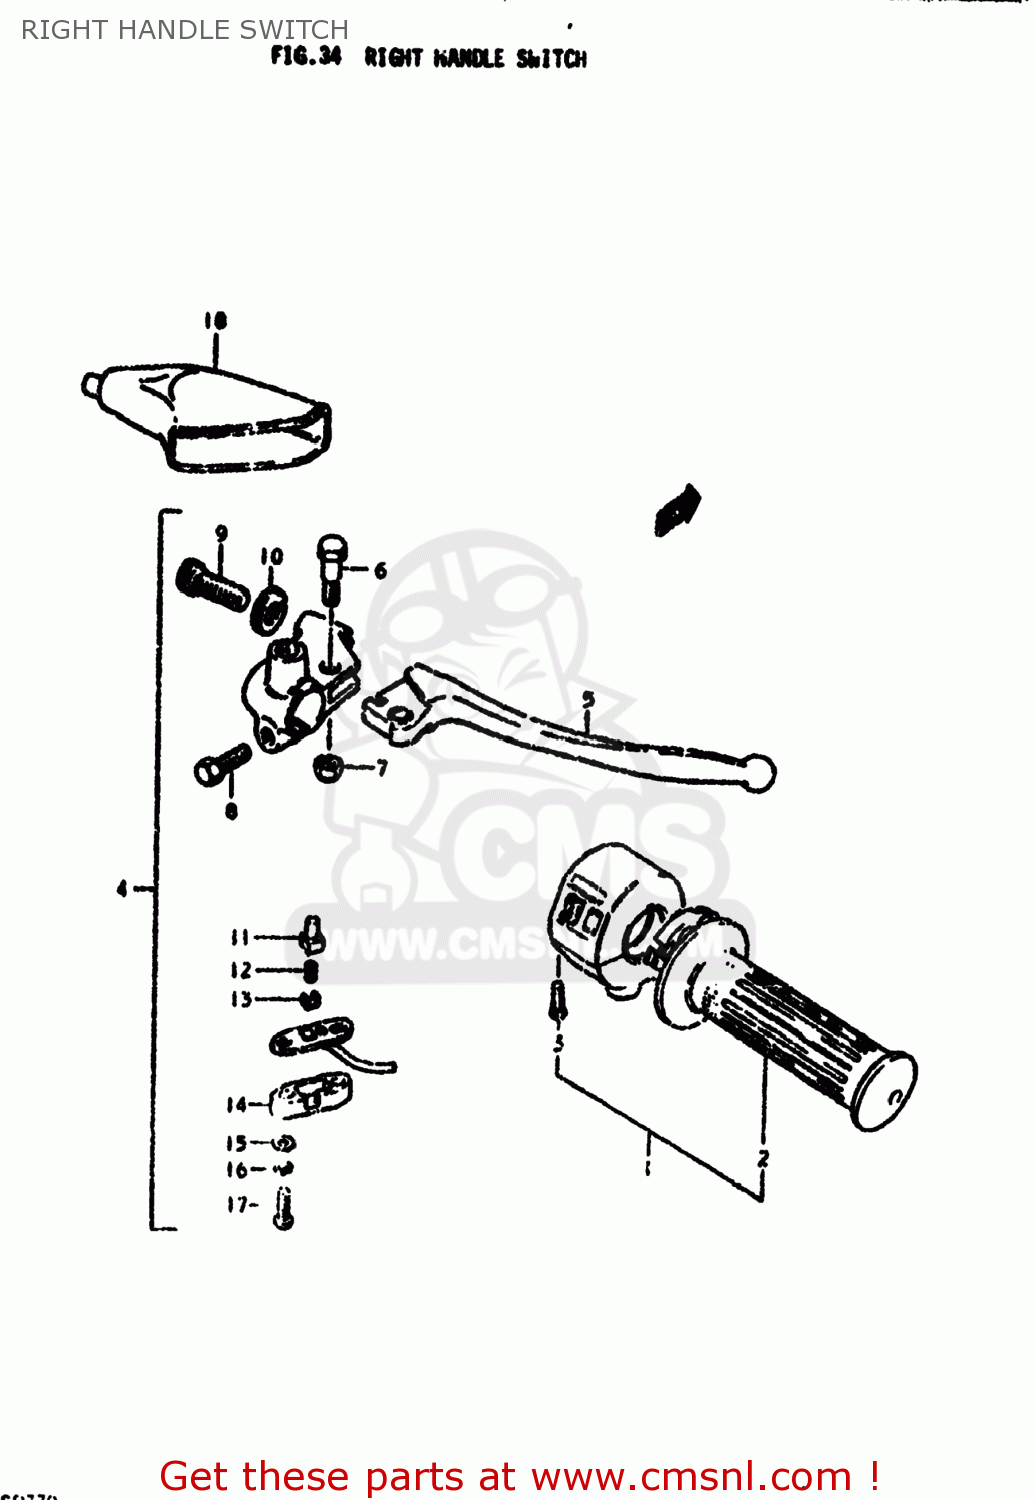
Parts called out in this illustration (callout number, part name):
1	CASE ASSEMBLY,THROTTLE
2	GRIP,THROTTLE
3	SCREW
4	BRAKE LEVER & SWITCH ASSY
5	LEVER,BRAKE
6	BOLT,LEVER
7	NUT 6MM
8	BOLT
9	ADJUSTER,CABLE
10	NUT,CABLE ADJUSTER
11	HOLDER
12	SPRING
13	PLATE
14	COVER,FR BK TERMINAL BASE
15	WASHER
16	LOCK WASHER
17	SCREW
18	COVER,CLUTCH LEVER
